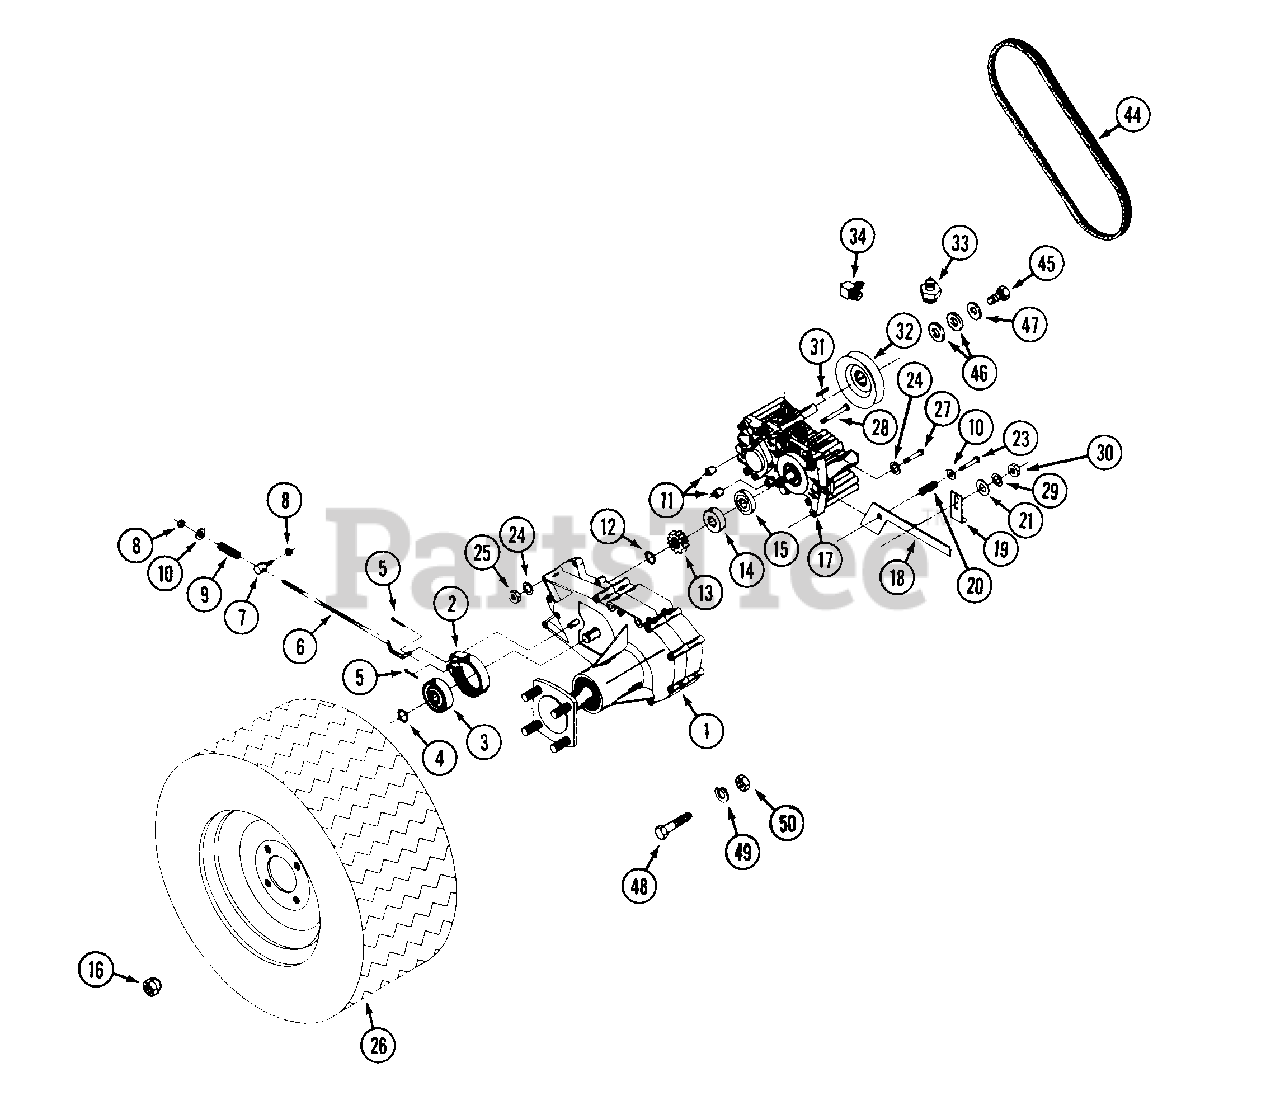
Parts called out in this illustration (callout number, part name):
1	TRANSMISSION - ZT
5	PIN - cotter 1/8" x 1"
7	COLLAR - brake rod
8	NUT - lock 1/4" - 20
10	WASHER - 1/4"
12	RING - snap
14	BEARING
16	NUT - lug 1/2" - 20
17	PUMP - hydro R.H.
18	LEVER - transmission dump R.H.
19	BRACKET - dump lever stop
20	SPRING - compression
21	WASHER - 3/8"
23	BOLT - dump valve
24	LOCKWASHER - 5/16"
25	NUT - 5/16" - 18
26	WHEEL ASSEMBLY
27	BOLT - 5/16" - 18 x 1-3/4"
28	BOLT - 5/16" - 18 x 7-1/2"
29	LOCKWASHER - 3/8"
30	NUT - 3/8" - 16
31	KEY - 5 x 5 x 25mm
32	PULLEY - 4" OD x 15 mm ID
33	ADAPTER -
34	ADAPTER - 90°.
44	BELT - pump drive
45	BOLT - M6 - 1.0 x 12m flange
46	WASHER - .626" x 1"
47	WASHER - .312" x .875"
48	BOLT - 3/8" - 16 x 3-1/2" mounting
49	LOCKWASHER - 3/8"
50	NUT - 3/8" - 16
